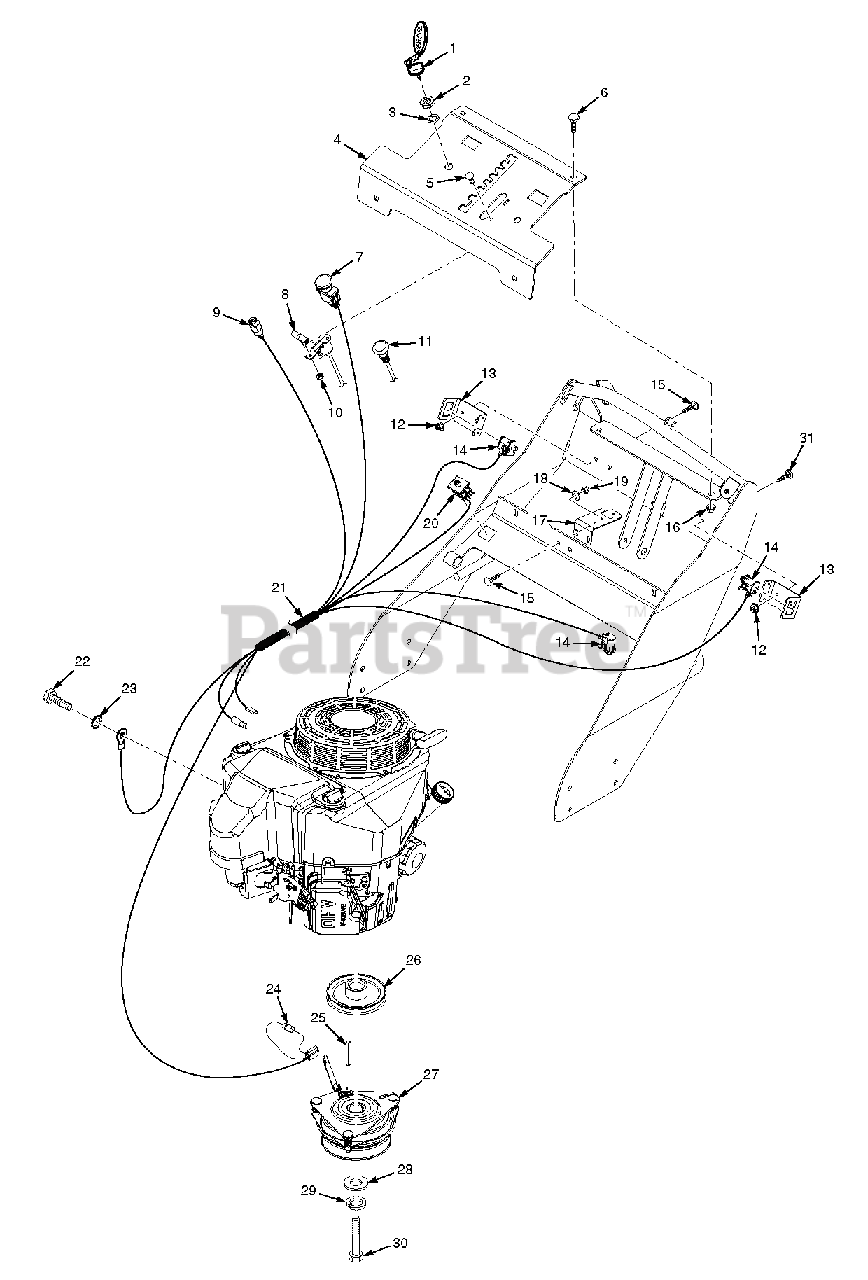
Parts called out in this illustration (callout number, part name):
1	Key Assembly w/Fob
1	Key w/Shroud
2	Nut, 5/8-32 Special
3	Lockwasher, 5/8" Internal Tooth
4	Instrument Panel w/Decal
5	Bolt, Carriage #10-24 x 1/2"
6	Bolt, Carriage 5/16-18 x 3/4"
7	PTO Switch
8	Throttle Cable
9	Key Switch
10	Nut, Elastic Stop #10-24
11	Choke Control
12	Nut, Serrated Flange 1/4-20
13	Bracket, Operator Presence Switch
14	Switch
15	Bolt, Carriage 1/4-20 x 3/4"
16	Nut, Serrated Flange 5/16-18
17	Bracket, Neutral Switch
18	Flatwasher, 5/16-.375 x .875 x .083
19	Nut, Elastic Stop 1/4-20
20	Switch, Brake Interlock
21	Wire Harness
22	Bolt, Hex Head M8-1.25 x 14
23	Lockwasher, 5/16" External Tooth
24	Diode
25	Key, 1/4 x 1/4 x 2-1/2"
26	Pulley, 4-1/2" Dia. 1" Bore
27	Electric Clutch Assembly
28	Flatwasher, 7/16-.469 x 1.75 x .25
29	Lockwasher, 7/16" spring
30	Bolt, Hex Head 7/16-20 x 3" w/t Patch
31	Bolt, Carriage 1/4-20 x 1-1/4"
